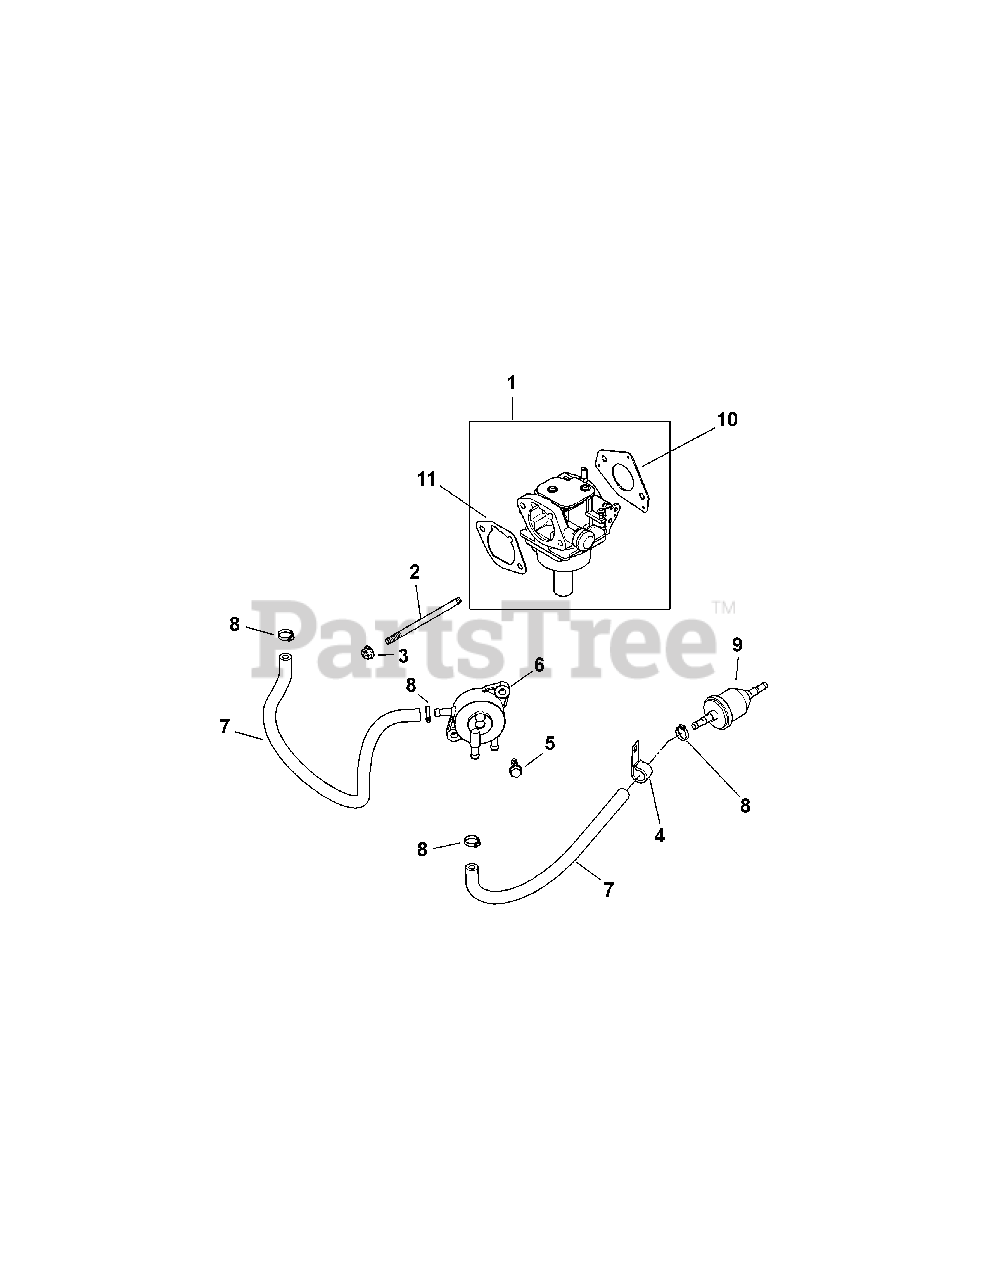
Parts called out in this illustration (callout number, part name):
1	Carburetor Kit
2	Stud, M6 x 1.0 x 106
3	Flange Nut, M6 x 1.0
5	Screw, M6 x 1.7 x 18
7	Fuel Line
8	Hose Clamp, 1/2
10	Carburetor Gasket
11	Air Cleaner Base Gasket
